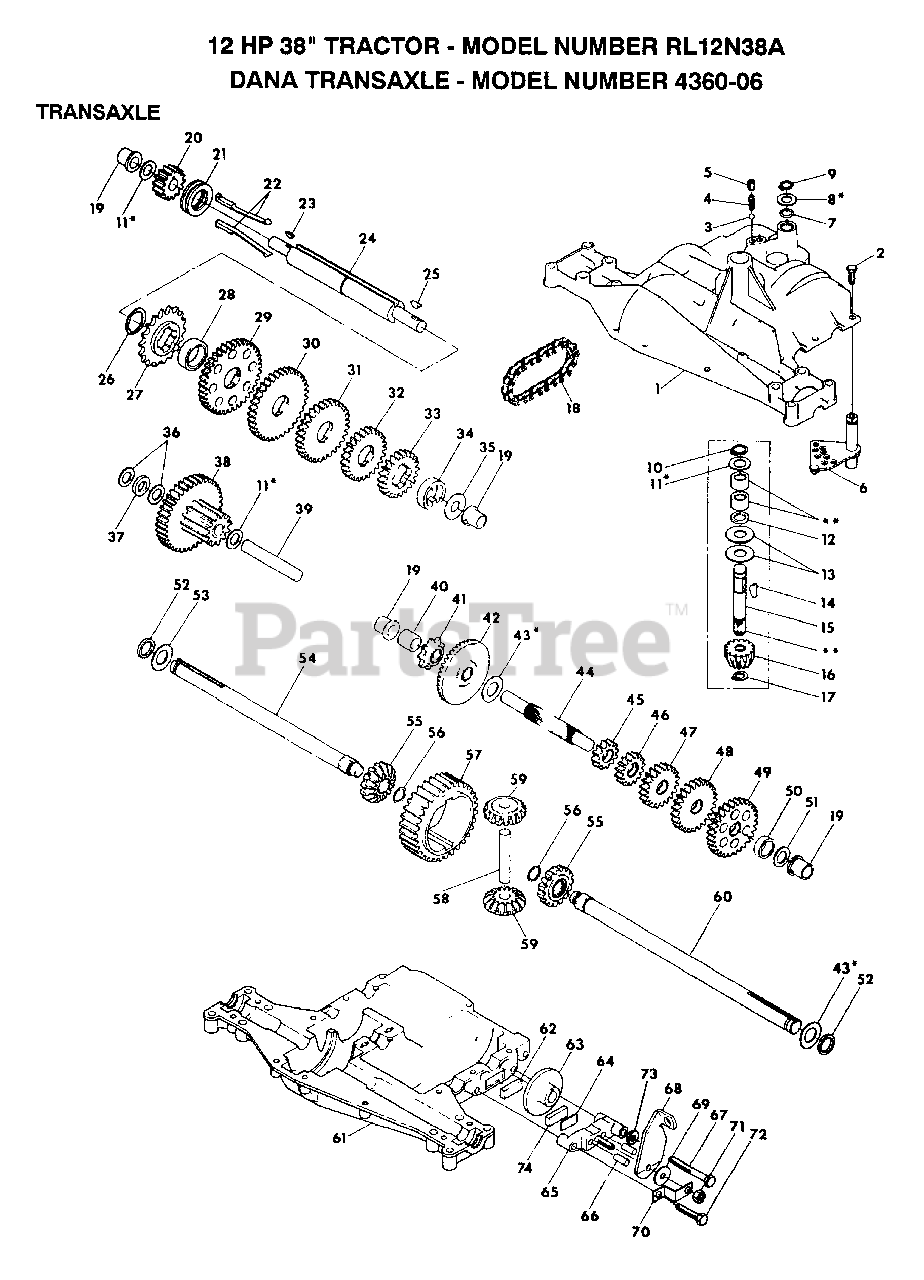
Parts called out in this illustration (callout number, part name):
1	HOUSING UPPER
3	BALL DETENT
4	SPRING, DETENT
5	SCREW, SET
6	ASSY SHIFTER
8	WASHER PLAIN
9	RING RETAINING
10	RING RETAINING
11	WASHER PLAIN
13	WASHER, PLAIN .632 X 1.38 X .046
14	KEY WOODRUFF #9
15	ASSY KIT INPUT SHAFT
16	PINION, BEVEL, 14 TEETH
17	RING, RETAINING
18	CHAIN, 24 PITCHES
19	BEARING, FLANGE
20	GEAR SPUR, 14 TEETH
21	COLLAR CLUTCH
22	KEY CLUTCH
23	KEY WOODRUFF #3
24	SHAFT INTERMEDIATE
25	KEY, WOODRUFF, #61
26	RING, RETAINING
27	SPROCKET, 18 TEETH
29	GEAR, SPUR, 37 TEETH
30	GEAR, SPUR, 30 TEETH
31	GEAR, SPUR, 25 TEETH
32	GEAR, SPUR, 22 TEETH
35	WASHER, PLAIN .640 X 1.37 X .061
36	WASHER, PLAIN .632 X 1.00 X .026
37	SPACER .630 X 1.00 X .169
38	ASSY GEAR COMB 12&35 TEETH
39	SHAFT IDLER
40	SPACER .635 X .875 X .755
41	SPROCKET, 9 TEETH
42	GEAR, BEVEL, 42 TEETH
43	WASHER PLAIN
44	SHAFT, DRIVE
45	GEAR, SPUR, 12 TEETH
46	GEAR, SPUR, 20 TEETH
47	GEAR, SPUR, 25 TEETH
48	GEAR, SPUR, 28 TEETH
49	GEAR, SPUR, 31 TEETH
51	WASHER, PLAIN .632 X 1.00 X .060
53	WASHER PLAIN
54	AXLE LEFT HAND
55	GEAR, MITER, 15 TEETH
56	RING, RETAINING
57	GEAR, SPUR, 32 TEETH
58	SHAFT, CROSS
59	GEAR, MITER, 15 TEETH
60	AXLE, R.H.
61	HOUSING LOWER
62	PUCK, FRICTION
63	DISC, BRAKE
65	JAW, BRAKE
66	PIN, DOWEL
67	SCREW TAPPING
68	LEVER, ACTUATING
69	WASHER, PLAIN .321 X 1.00 X .055
70	BRACKET, ANTI-ROTATION
71	LOCKNUT 5/16-24
72	SCREW TAPPING
73	WASHER PLAIN
74	PUCK, FRICTION
